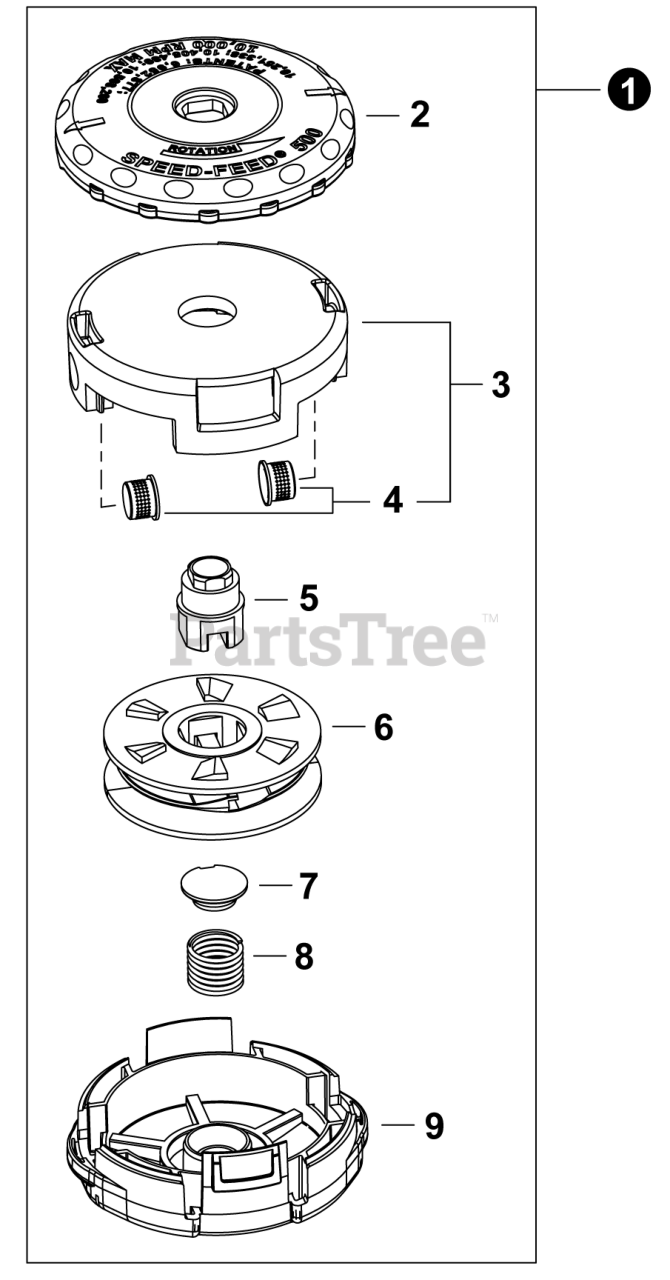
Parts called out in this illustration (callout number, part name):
1	TRIMMER HEAD, SPEED-FEED® 500
3	HOUSING ASSY, SPOOL
5	BUSHING 10MMx1.25 LH BLUE
6	SPOOL LH
7	CAP, SPRING
8	SPRING, GOLD
9	COVER, SPOOL
